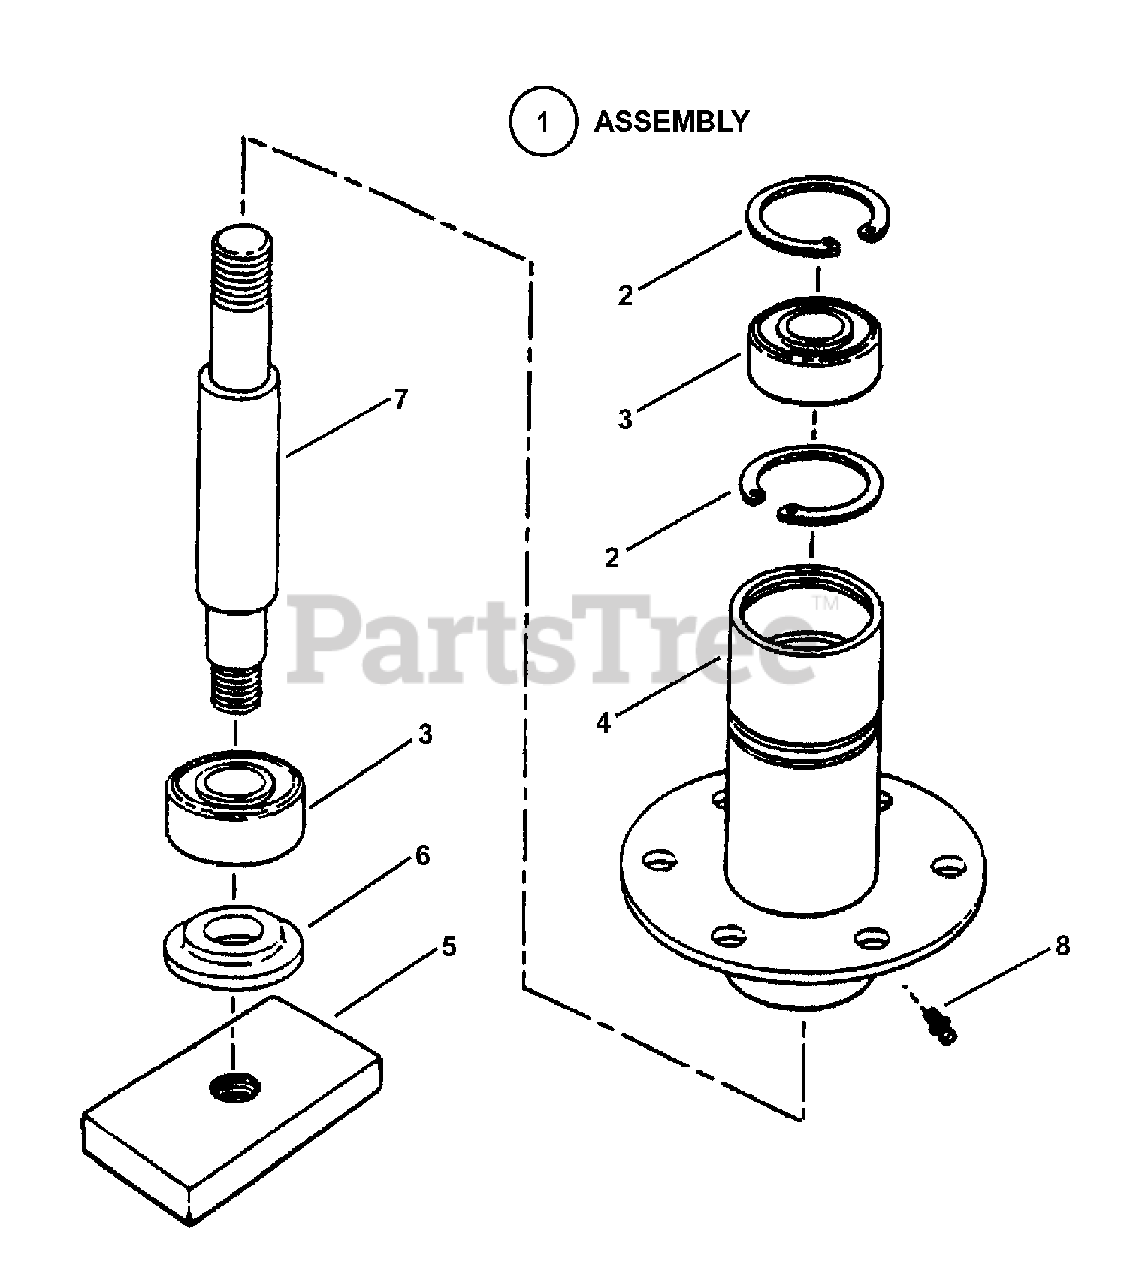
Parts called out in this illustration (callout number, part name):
1	ASSEMBLY, Spindle, Brake
2	RING, 1-3/4" External Retaining Ring
3	BALL BEARING, 3/4" I.D.
4	WELDMENT, Spindle Housing
5	BLADE HOLDER (3/4-16 Internal Thread)
6	WASHER, Spindle
7	SHAFT, Blade Spindle (3.47" shanl length)
8	FITTING, Lube, Press-In (for .187 dia. Hole)
